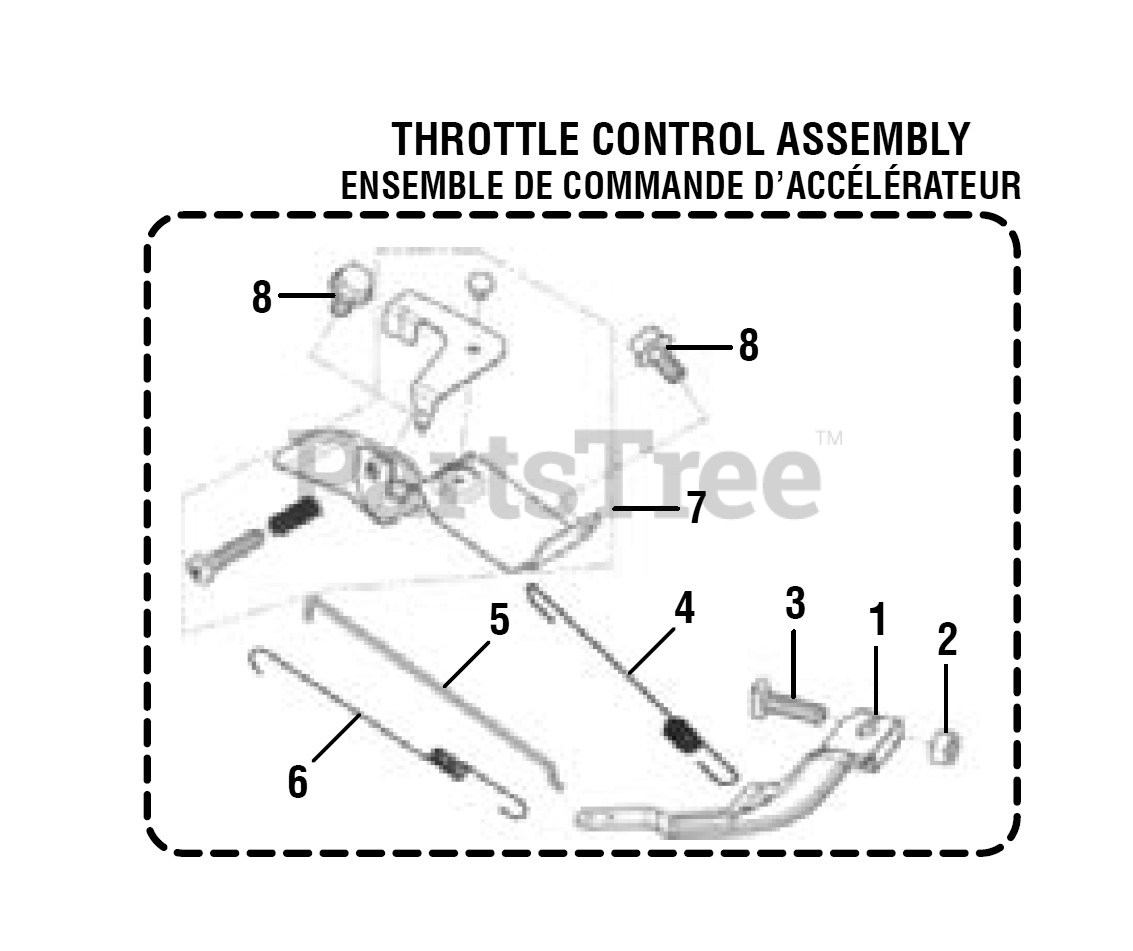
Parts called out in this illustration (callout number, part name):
1	Governor Support Assembly
3	Governor Support Bolt
4	Governor Spring
5	Governor Rod
6	Throttle Valve Return Spring
7	Throttle Control Assembly
